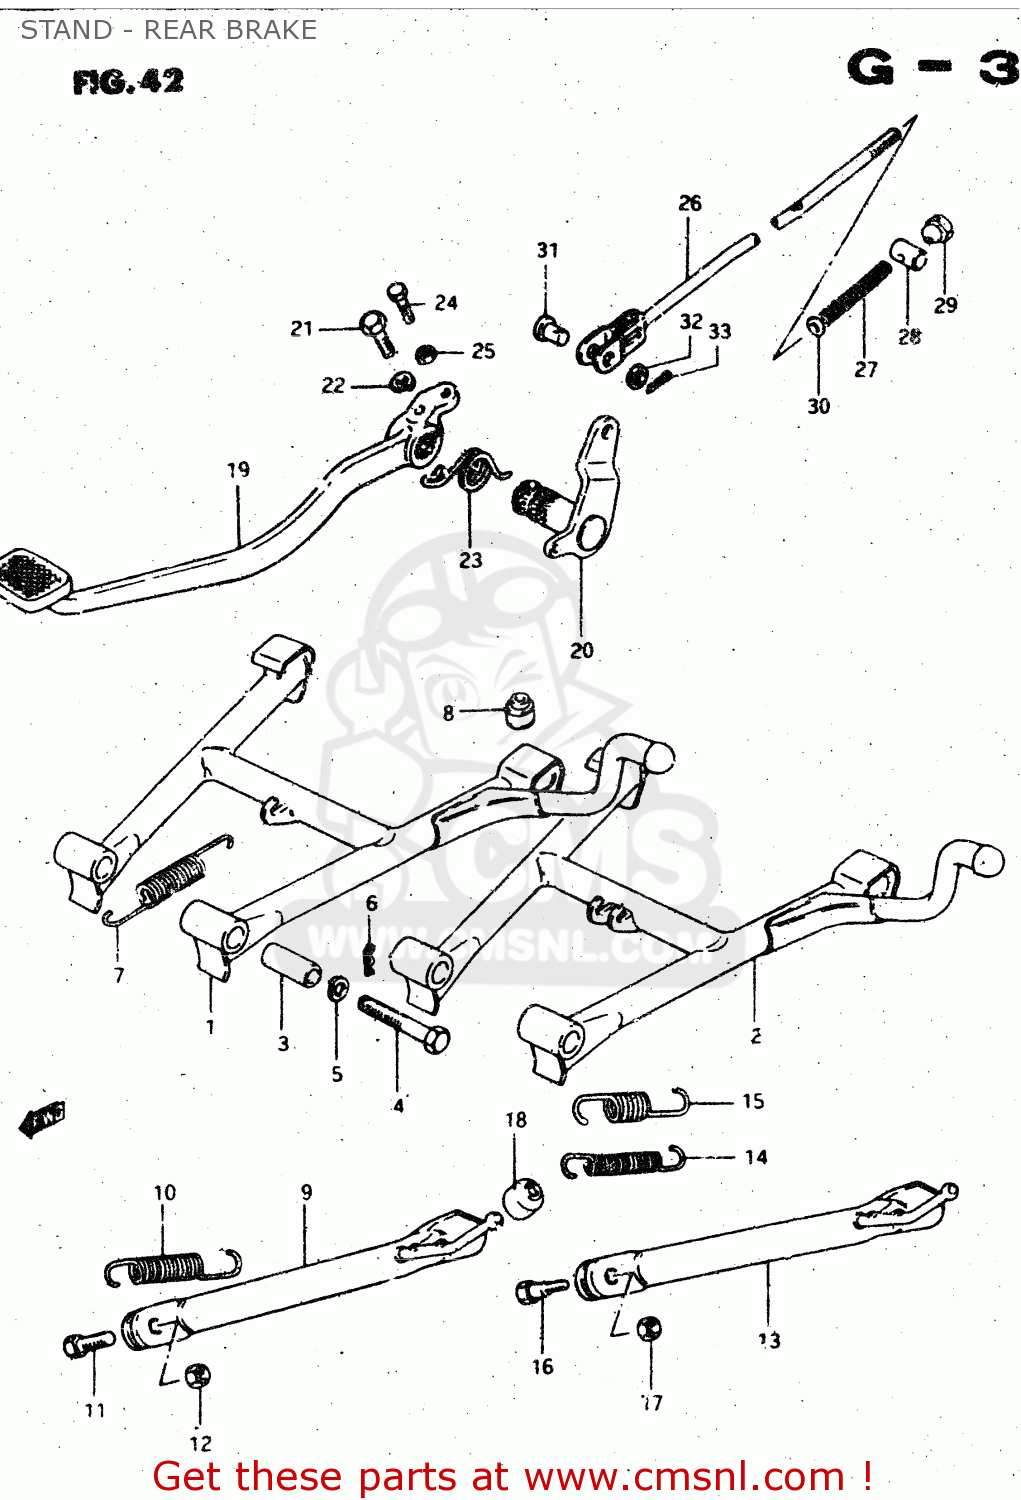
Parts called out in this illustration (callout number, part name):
1	STAND,CENTER
2	STAND, CENTER
3	SPACER(10X16X38.8)
4	BOLT
5	LOCK WASHER
6	CLIP
7	SPRING
8	CUSHION
9	STAND,SIDE
10	SPRING
11	BOLT(10X30)
12	NUT
13	STAND, PROP
14	SPRING
15	SPRING, OUTER
16	BOLT
17	NUT
18	CUSHION
19	PEDAL,BRAKE
20	ARM,BRAKE PEDAL ROD
21	BOLT
22	LOCK WASHER
23	SPRING
24	BOLT
25	NUT
26	ROD ASSY, REAR BRAKE
27	SPRING
28	PIN
29	NUT
30	WASHER
31	PIN(L:13.5)
32	WASHER
33	PIN 20X20
